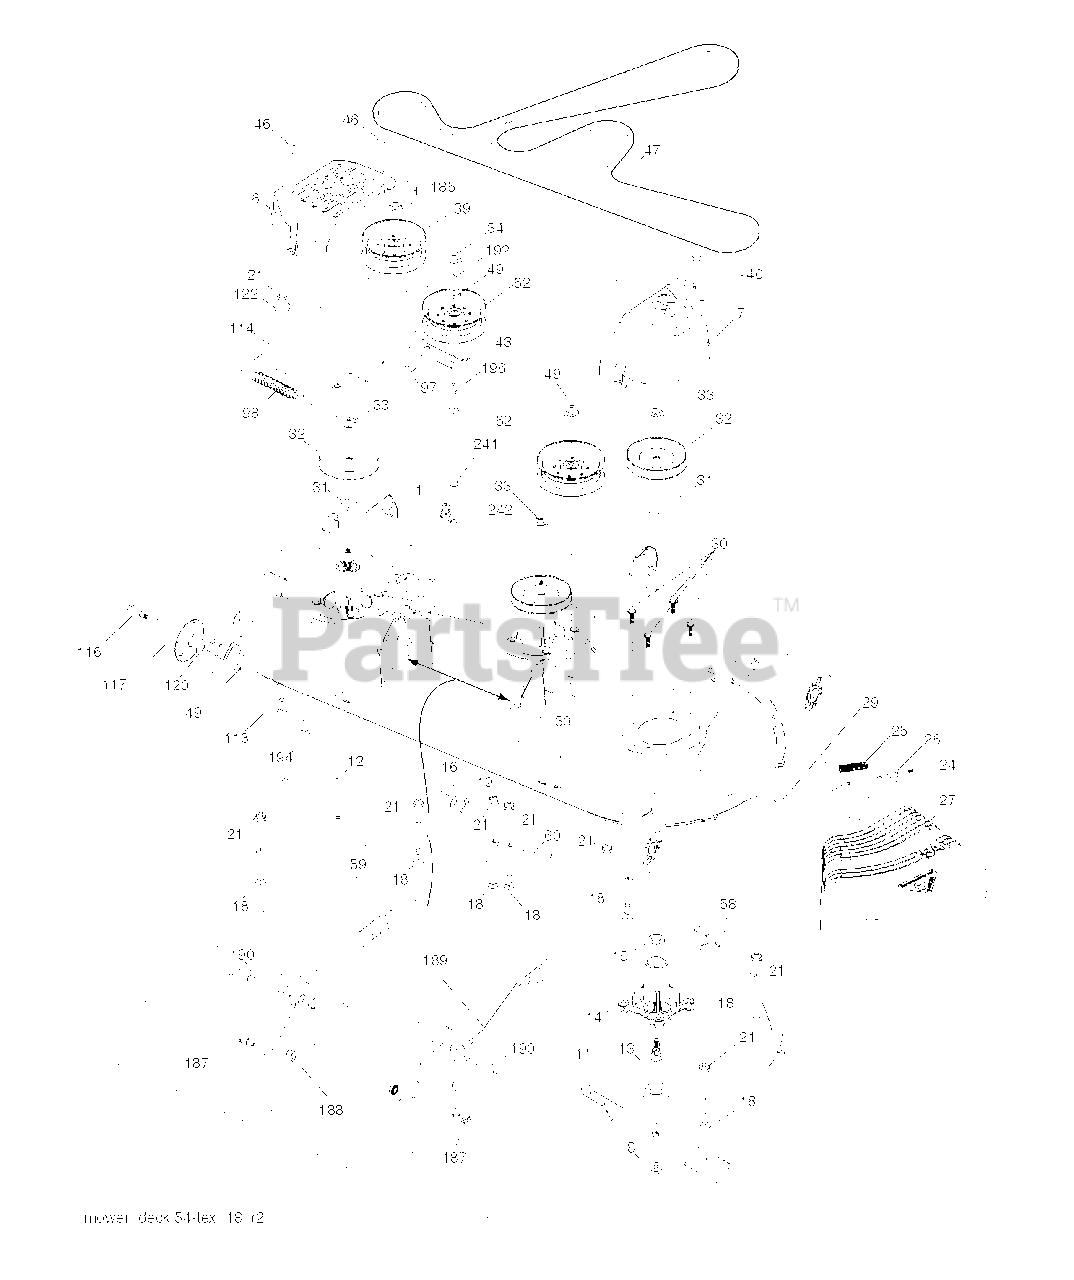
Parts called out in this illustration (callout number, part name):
1	DECK.WELDMENT.54"MS-666
6	COVER.MANDREL.LH.54"20
7	COVER.MANDREL.RH.54.20
8	BOLT.WASHER.ASM.7/16-2
11	BLADE, BAGGING 54''
12	ROD.ANTI.SWAY.48/54"TE
13	SHAFT ASM MANDREL
14	HOUSING MANDREL
15	BEARING
18	BOLT
19	PIN.COTTER.5/16.BOW TI
24	CAP-SLEEVE LT
25	SPRING, TORSION
26	NUT PUSH M
27	DEFLECTOR
29	HINGE ROD
30	SCREW, WASHER HEAD
32	PULLEY/MANDREL
33	NUT.FLANGE.LOCK.TOP
34	LOCKNUT
39	PULLEY.IDLER.4.50/HUB SPECIAL
43	ARM.IDLER
46	SCREW 1/4-20X5/8
47	BELT.DRIVE.54."2006
58	BAFFLE RIGHT
59	BAFFLE LEFT
60	BAFFLE CENTER 54" MOWER
98	SPRING.DRIVE.DECK.2006
113	BOLT CRT
114	ROD TENSION RELIEF
116	BOLT.SHOULDER.3/8-16X3-5/8
117	WHEEL. GUAGE RALLY
120	WASHER
122	BUSHING
185	NUT.LOCK.FLANGE.7/16
187	STUD.FASTNER.W/D.ANTI-
188	NUT LOCK HEX FLANGE 5/16-18
189	ARM.SUSPENSION.MOWER
190	BOLT.SHOULDER
192	KEEPER.BELT.IDLER.54"T
242	PORT.WASHOUT
